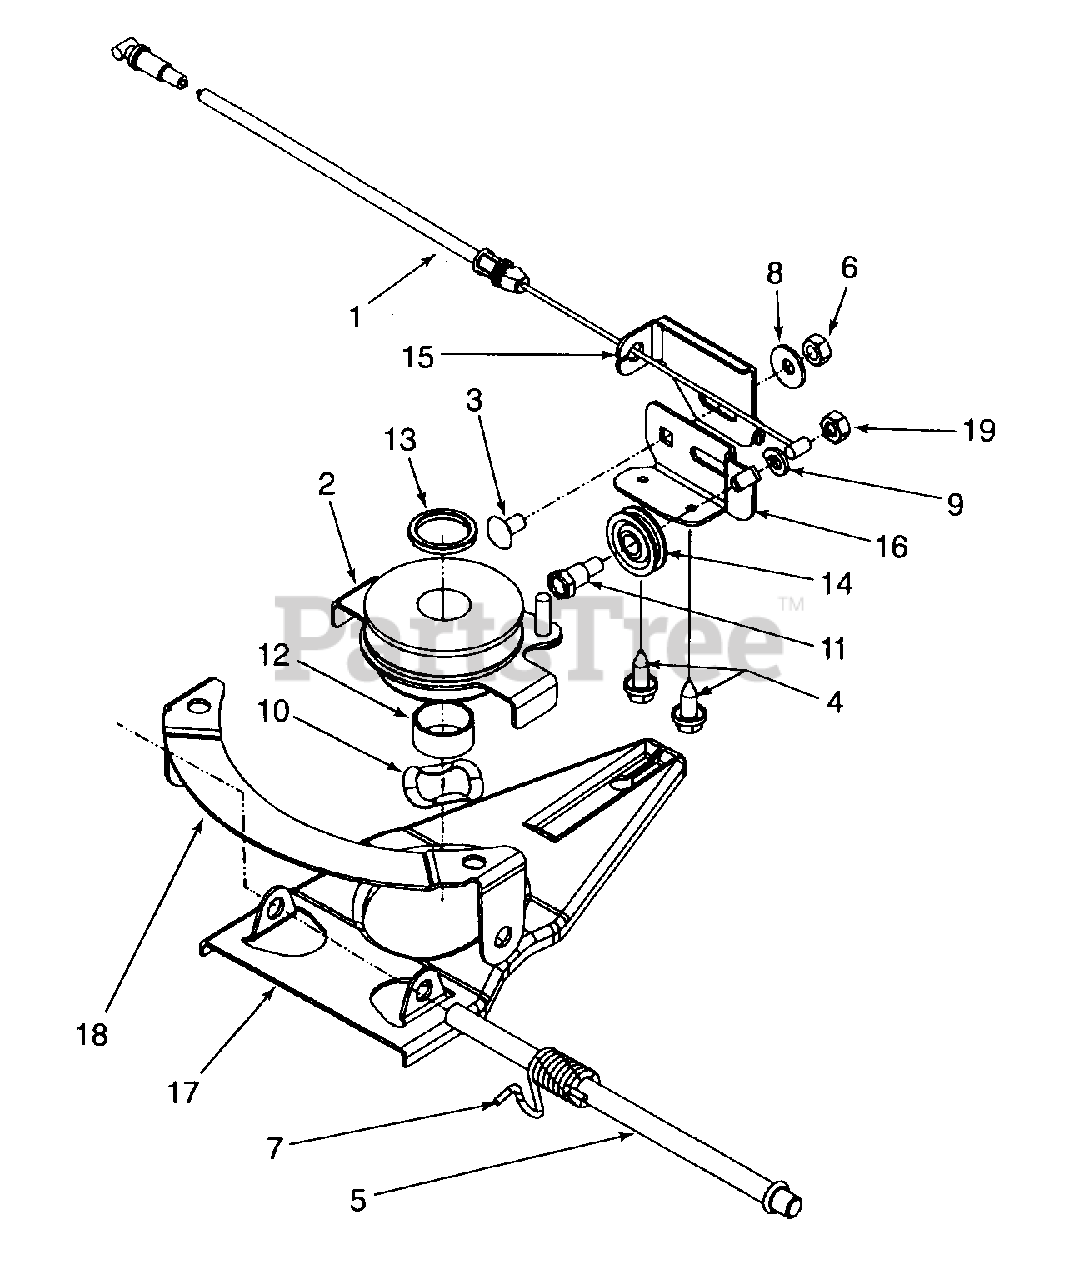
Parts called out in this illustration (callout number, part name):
1	6 Spd. Cable
2	Pulley Ass'y Mult - Spd.
3	Scr. 1/4-20 x .50 Carr.
4	Scr. AB 1/4-14 x .625 Hex hd. Wsh.
5	Pivot Shaft
6	Nut 1/4-20
7	Torsion Spring LH
8	Bell Wash. .265 X .75 X .062
9	Lock Wash. 1/4 Reg Duty
10	Wave Wash. 1.38 x.88 x.029
11	Shld. Scr. .375 x 1/4 -14AB
12	Slev Spcr. .88 ID 1.00 OD x.48
13	Slev Spcr. .88 ID x 1.13 ID x.12
14	Roller Cable
15	6 Spd. Cable Adj. Bracket
16	6 Spd. Cable Mt. Bracket
19	Hex Nut 1/4-28
